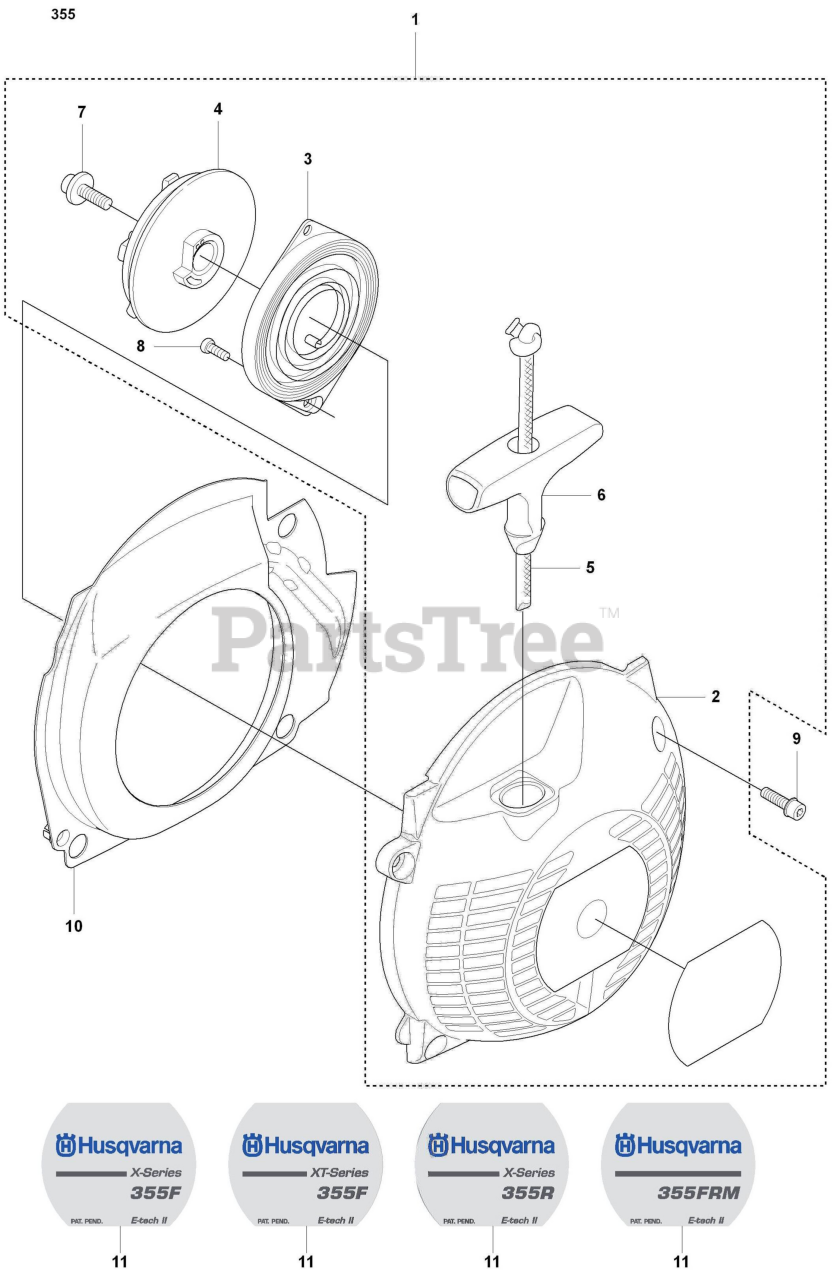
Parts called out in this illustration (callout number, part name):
1	STARTER
2	STARTER HOUSING
3	RECOIL SPRING
4	STARTER PULLEY
5	STARTER ROPE
10	AIR CONDUCTOR
11	LABEL
